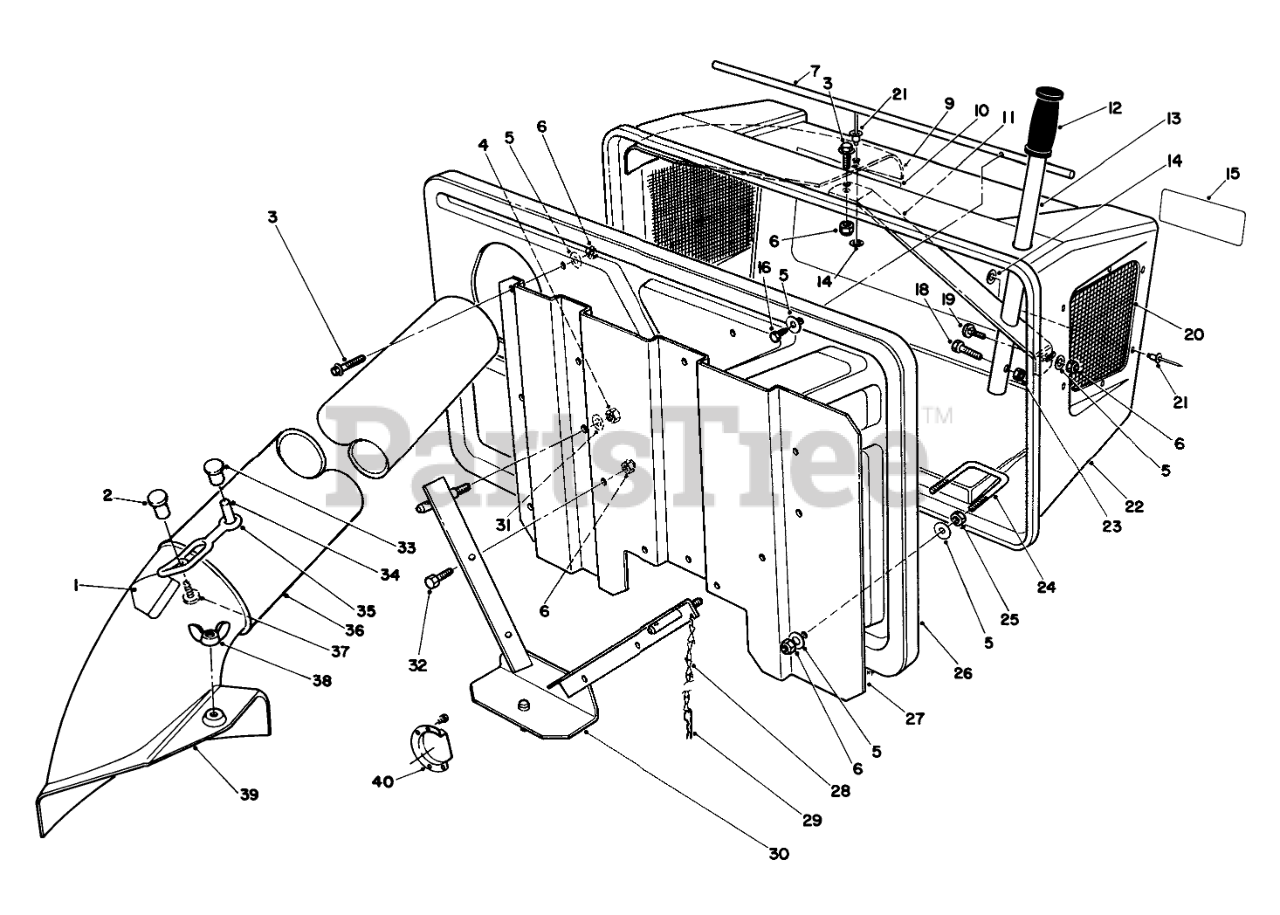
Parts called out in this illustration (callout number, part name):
1	DECAL-DANGER
3	SCREW-HHF
4	NUT-LOCK, NI
5	WASHER-FLAT
6	NUT-LOCK, NI
7	PIVOT ROD
9	DEFLECTOR
10	DECAL
11	HANDLE GUIDE
13	HANDLE TUBE
14	WASHER-FLAT
15	EASY EMPTY BAG DECAL
16	SCREW-HH
18	SCREW-HH
19	BOLT-CARR
20	SCREEN
21	RIVET-POP
22	HOPPER
23	NUT-HEX, SIDE DEFORM
24	LATCH
25	NUT-HEX
27	Plate-Mounting
28	6-LINK CHAIN W/HOOK
29	PIN-HAIR
30	V-Bracket
31	WASHER-FLAT
32	SCREW-HH
33	FASTENER-PANEL
34	SPACER-INTERLOCK
35	RETAINER-DUCT
37	Screw
38	NUT-WING SPECL
39	Chute (Incl. Ref. #1, 2 & 37)
40	MUFFLER DEFLECTOR
